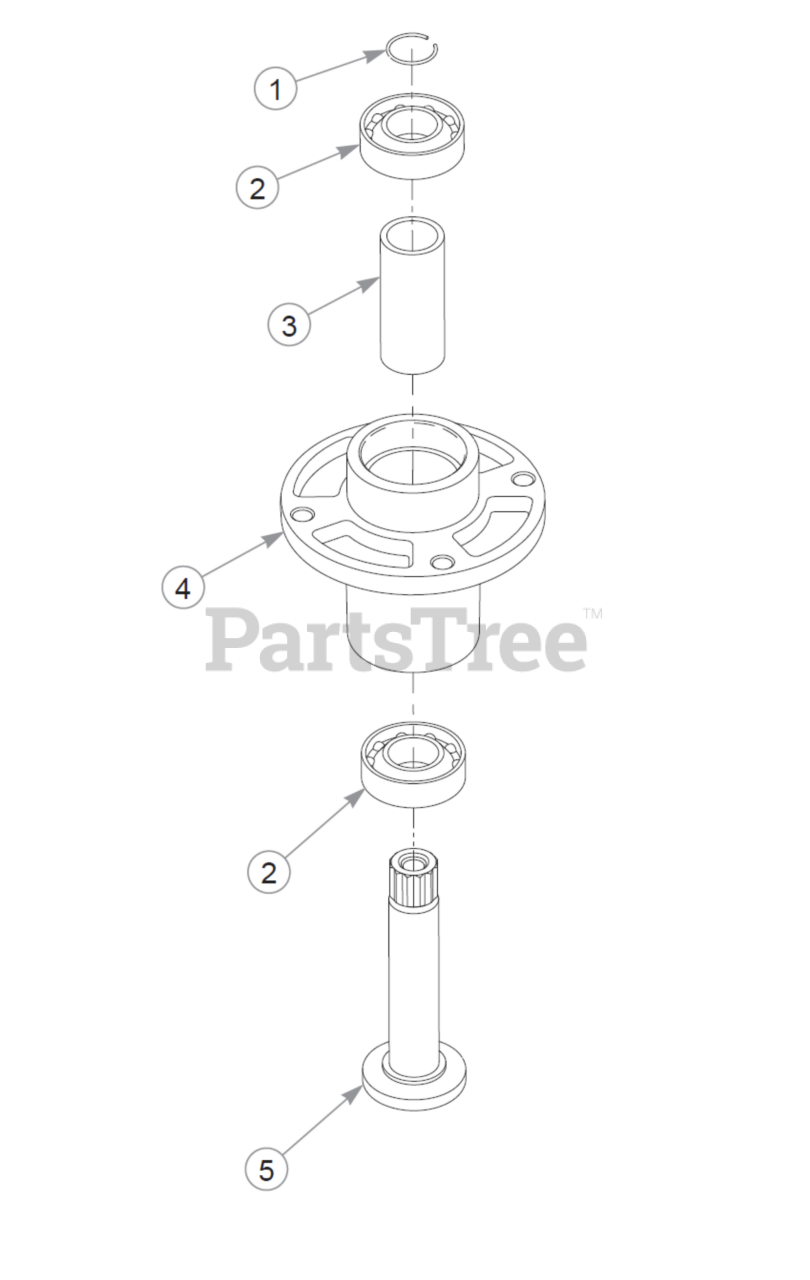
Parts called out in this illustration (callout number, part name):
1	RING, BLADE SPINDLE RET
2	BEARING, 6205 2RST C3
3	SPACER, BLADE SPINDLE
4	HOUSING, BLADE SPINDLE
5	SHAFT, BLADE SPINDLE
601804	BLADE SPINDLE ASSY
